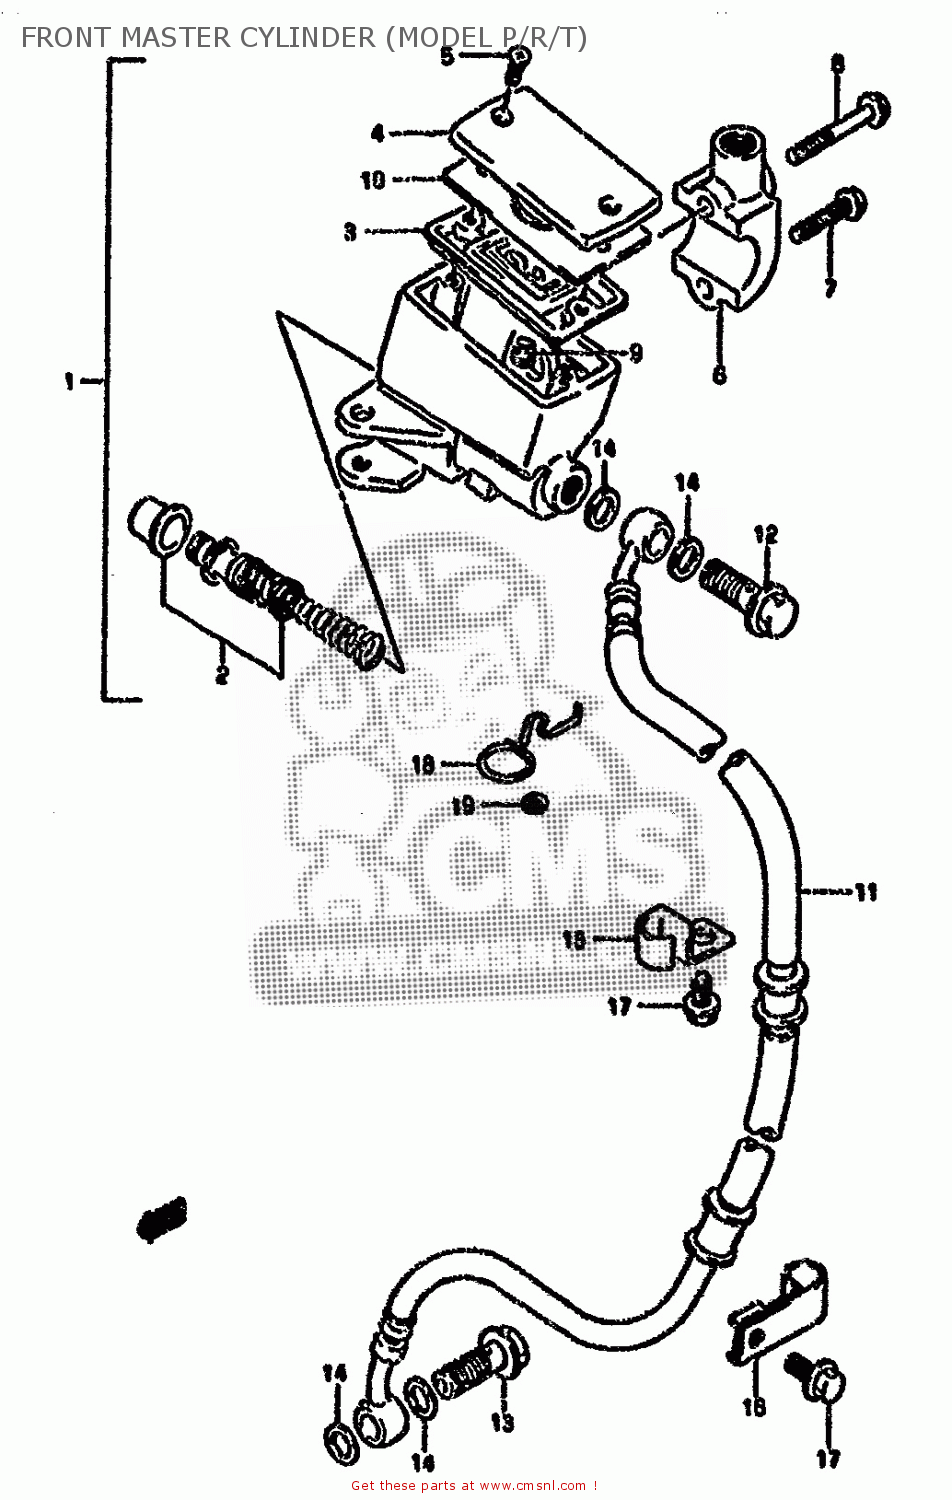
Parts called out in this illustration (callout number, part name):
1	CYLINDER ASSY,FR MASTER
2	PISTON/CUP SET
3	4
4	CAP
5	SCREW
6	HOLDER
7	BOLT(6X25)
8	BOLT(6X38)
9	PROTECTOR
10	PLATE,DIAPHRAGM
11	HOSE,FR BRAKE
12	BOLT UNION
13	BOLT UNION
14	WASHER(10X15X1.5)
15	CLAMP,FR BRAKE HOSE NO.1
16	CLAMP,FRONT BRAKE NO.2
17	BOLT
18	GUIDE,FRONT BRAKE HOSE
19	WASHER
